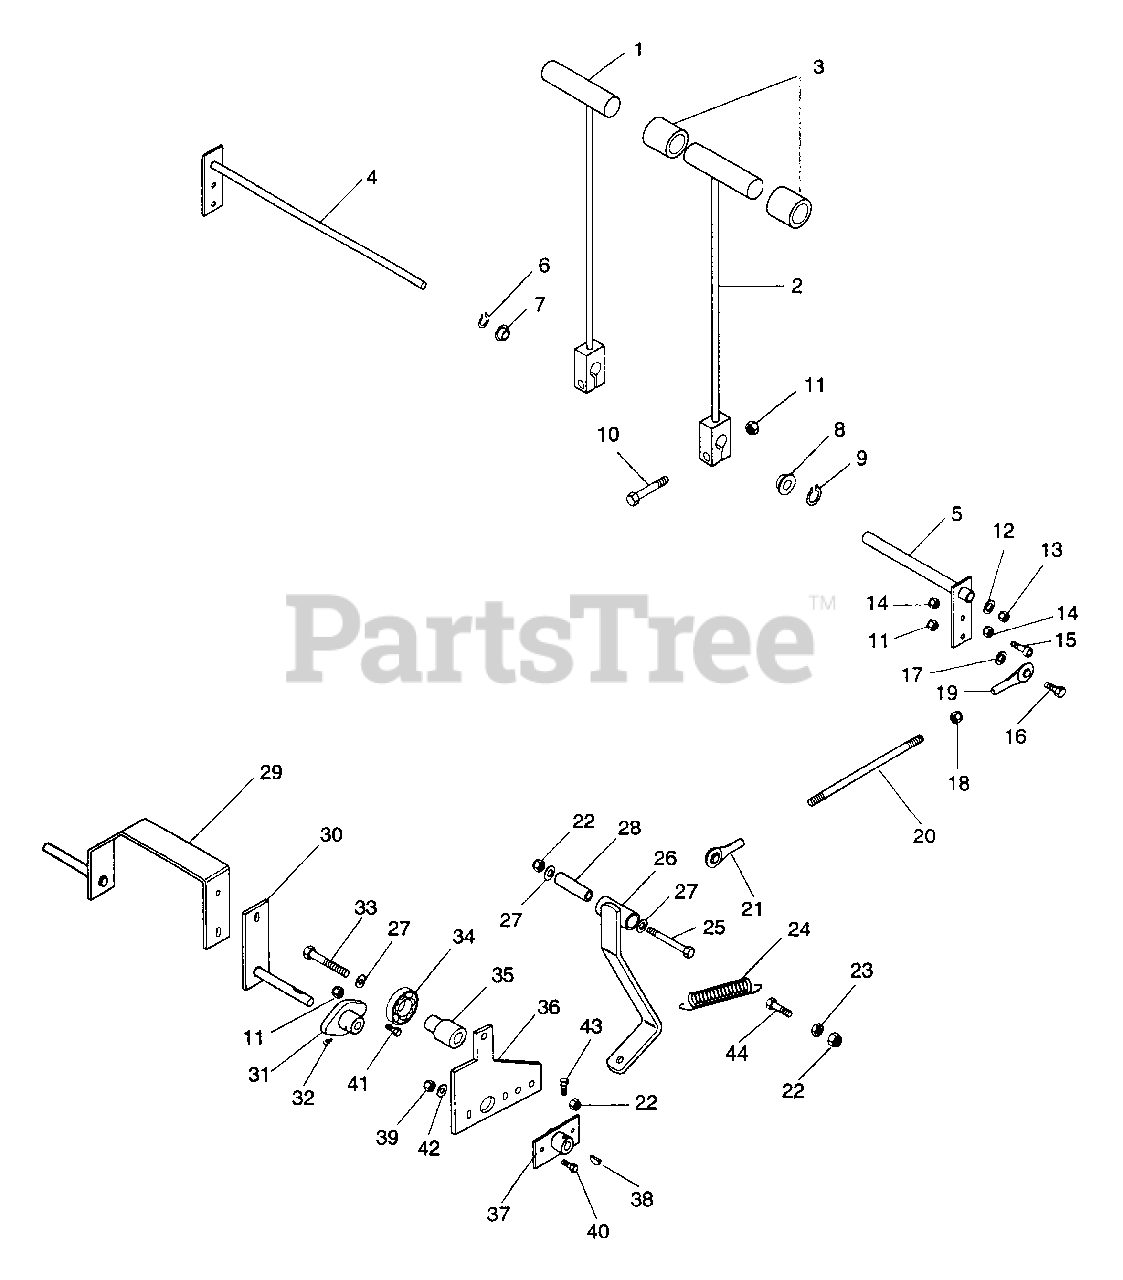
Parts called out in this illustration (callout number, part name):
1	Weldment, Steering Lever L.H.
2	Weldment, Steering Lever R.H.
3	Grip, T-Bar
4	Weldment, Steering L.H.
5	Weldment, Steering Tube R.H.
6	Ring, Retaining
7	Bushing, Flange .515 x 1.00 x .745 Nylon
8	Bushing-Flange .762 x 1.0 x .580 x 1.48 Nylon
9	Ring-Retaining-External .689 x .077
10	Bolt-Hex .31-18 x 1.50 PL Gr. 5
11	Nut-Lock-Nylon .312-18 PL
12	Washer-Flat-Steel .531 x 1.062 x .095
13	Nut-Lock Nylon .50-13 PL
14	Nut-Hex .312-18
15	Screw-Set .32-18 x 1.50 Skhcup
16	Bolt-Hex .31-18 x 1.25 PL Gr. 2
17	Washer-Flat-Steel .344 x .688 x .065 PL
18	Nut - 5/16-24, Hex, Plated
19	Rod End 5/16 Female
20	Rod, Steering Adjustment
21	Rod End, 5/16 - 24 L.H. Female
22	Nut-Lock-Nylon .375-16 PL
23	Nut-Hex .375-16
24	Spring, Tension
25	Bolt-Hex .38-16 x 2.75 Pl Gr. 5
26	Weldment, Neutral Detent
27	Washer-Flat-Steel .406 x .812 x .065 PL
28	Bushing.385 x .610 x 1.80
29	Weldment, Pump Control R.H.
30	Weldment, Pump Control L. H.
31	Bushing, Flange Support
32	Fitting-Lube .25-28 Self-Thread
33	Bolt-Hex .38-16 x 2.00 PL Gr. 5
34	Bearing-Ball .500 x 1.375 x .437
35	Hub, Bearing Mount
36	Arm-Speed Control
37	Weldment, Neutral Adjustment
38	Key, Woodruff 1/8 x 3/4
39	Nut-Lock-Nylon .250-20 PL
40	Bolt-Hex .25-20 x .75 Pl Gr. 5
41	Bolt-Hex .31-18 x 1.00 PL Gr. 5
42	Washer-Flat-Steel .281 x .62 x .065 PL
43	Bolt-hex .25-25 x .50
44	Bolt-Hex .38-16 x 1.125
